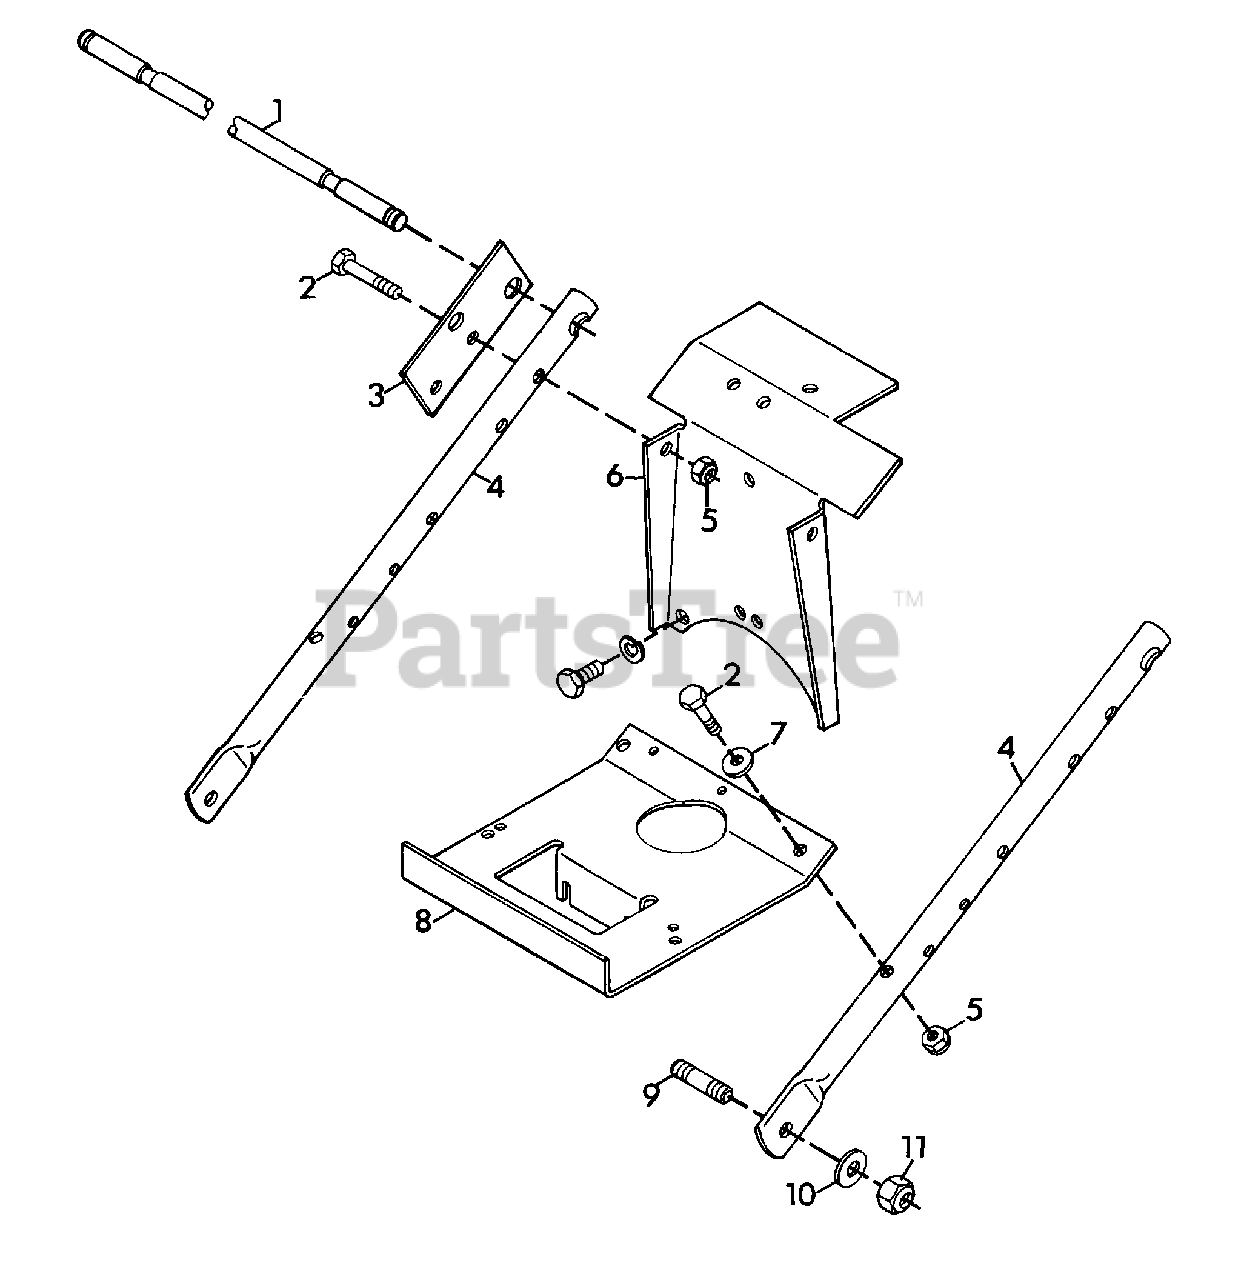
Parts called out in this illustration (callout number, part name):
1	SHAFT, CROSS
2	BOLT, HEX 3/8-16X2.25
3	BRACKET, INTERLOCK
4	TUBE, SUPPORT
5	NUT, LOCK 3/8-16
6	SHIELD, HEAT
7	WASHER, FLAT .406X.812X.065
8	BOX, BATTERY
9	STUD
10	WASHER, FLAT .531X1.062X.095
11	NUT, LOCK 1/2-13
